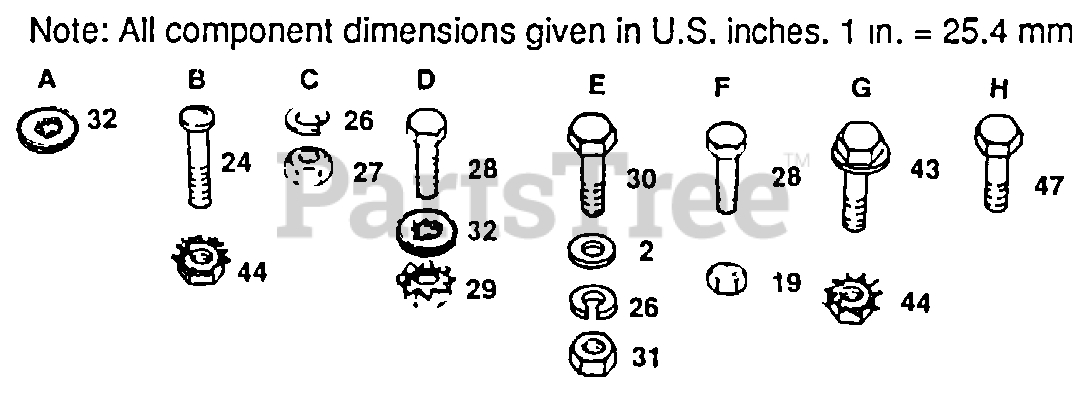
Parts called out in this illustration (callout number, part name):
2	WASHER
26	LOCKWASHER
27	NUT
28	BOLT
29	NUT
30	BOLT LT
43	SCREW
44	"NUT,KEPS"
47	SCREW
